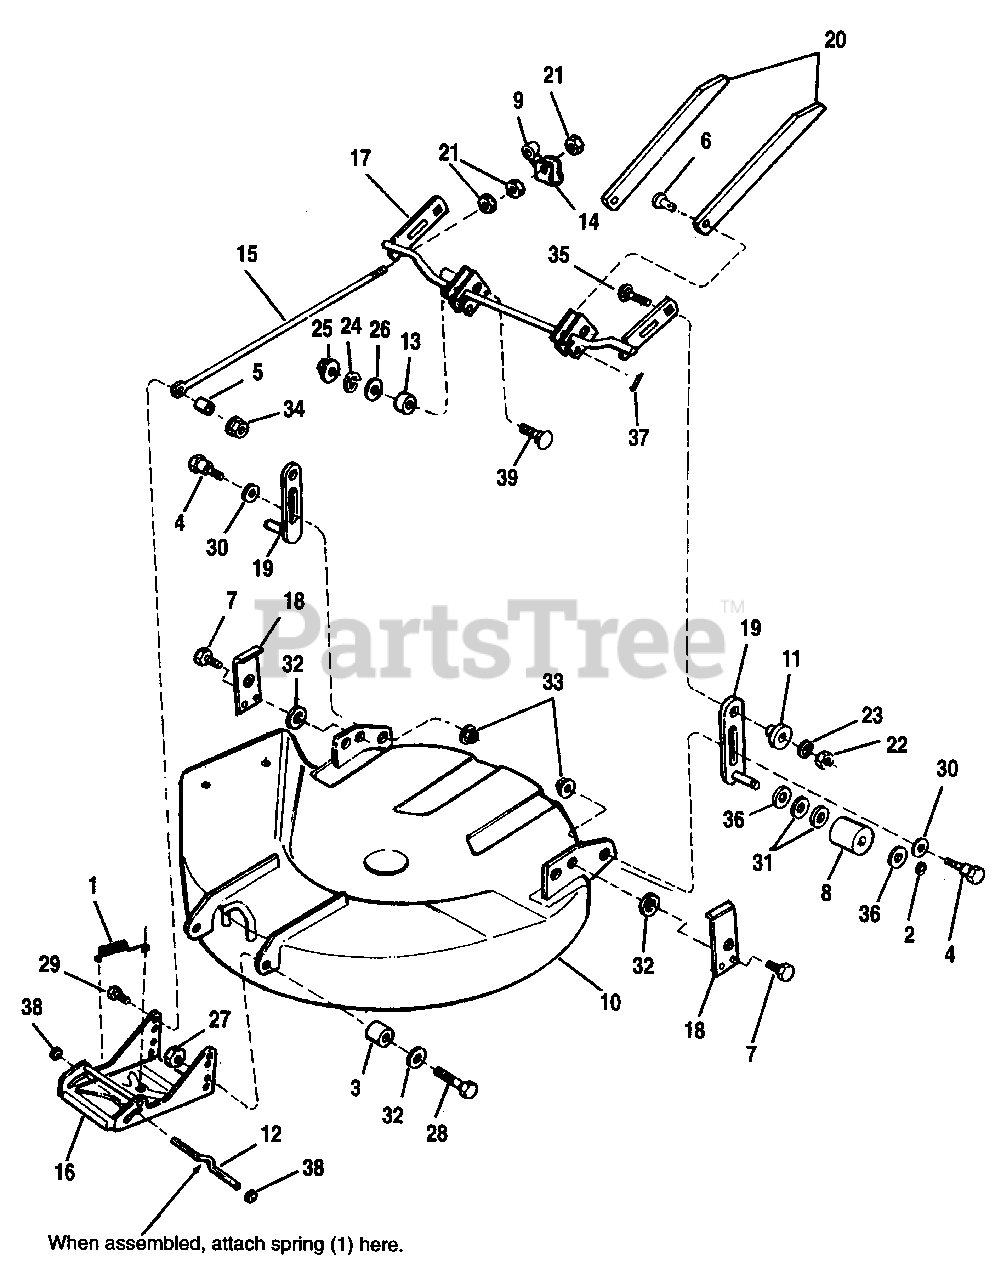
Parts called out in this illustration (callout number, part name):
2	RING, Retaining
4	BOLT, Shoulder, 3/8-16 X 1.34
6	PIN, Locking
7	SCREW, Taptite, 5/16-18 x 3/4
9	SPACER
10	HOUSING ASSY., 30" (Orange)
10	HOUSING ASSY., 30" (Black)
11	NUT, Hex Adjusting, .99 DIA .687
12	ROD, Latch, Hitch
15	ROD, Adjustment
16	HITCH ASSY.
17	ARM ASSY., Mower
18	PLATE, Pivot Support
19	SUPPORT ASSY., Roller
20	BAR, Mower Transport
21	JAMNUT, Hex, 1/2-13
22	NUT, Hex, 3/8-16
23	LOCKWASHER
24	LOCKWASHER, 5/16
25	NUT, Hex, 5/16-18
26	WASHER, Flat, 5/16
27	LOCKNUT, Hex, 3/8-16
28	CAPSCREW, Hex, 3/8-16 x 1-1/4
29	CAPSCREW, Hex Hd., 3/8-16 x 1
30	WASHER, Flat
31	WASHER, 5/8
32	WASHER, Flat, 3/8
33	NUT, Hex, Flange, Whizlock, 3/8-16
34	NUT, Hex, Flange Lock, 3/8
35	CARRIAGE BOLT, 3/8-16 x 1-1/2
36	WASHER, 21/32 x 1-1/8 x 1/16
37	PIN, Retaining
38	PUSHNUT
39	CARRIAGE BOLT, 5/15-18 x 1-1/4
